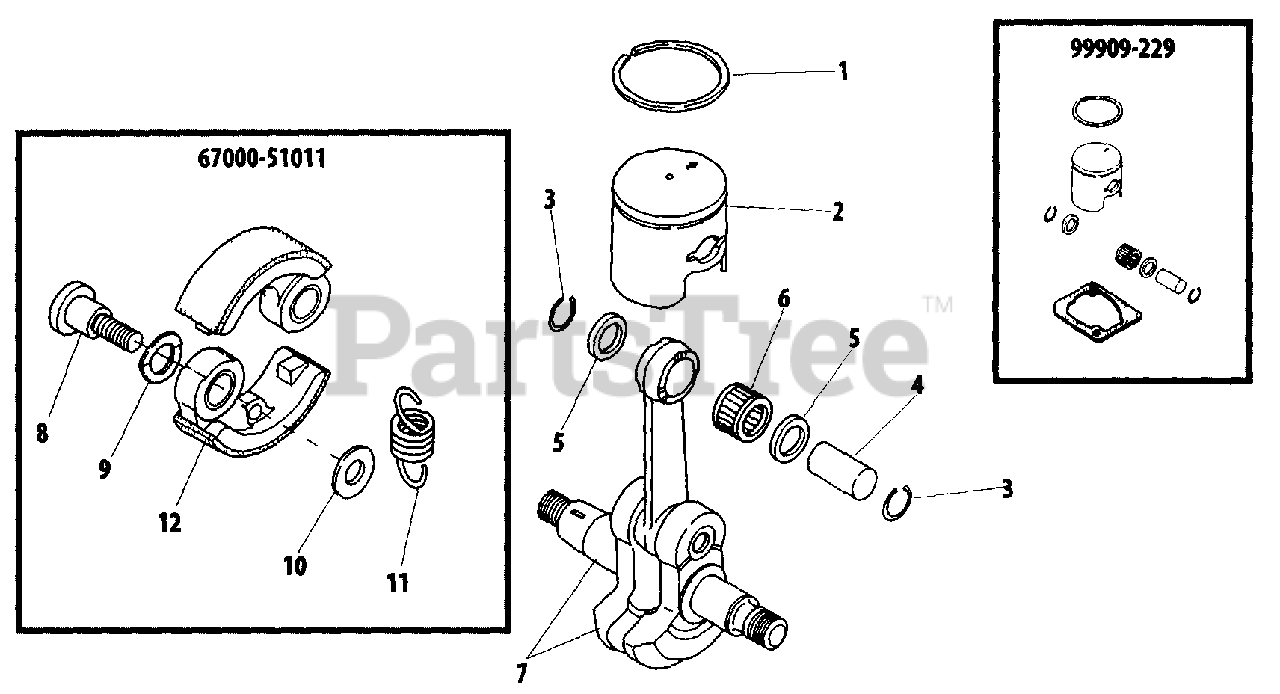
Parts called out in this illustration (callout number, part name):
1	RING, PISTON
2	PISTON
3	RING, RETAINING
4	PIN, PISTON
5	WASHER, THRUST
6	BEARING, NEEDLE
7	CRANKSHAFT ASSY
8	BOLT, CLUTCH
9	WASHER - SPRING
10	WASHER - 6
11	SPRING, CLUTCH
12	SHOE, CLUTCH
67000-51011	CLUTCH ASSY
99909-229	PISTON KIT
